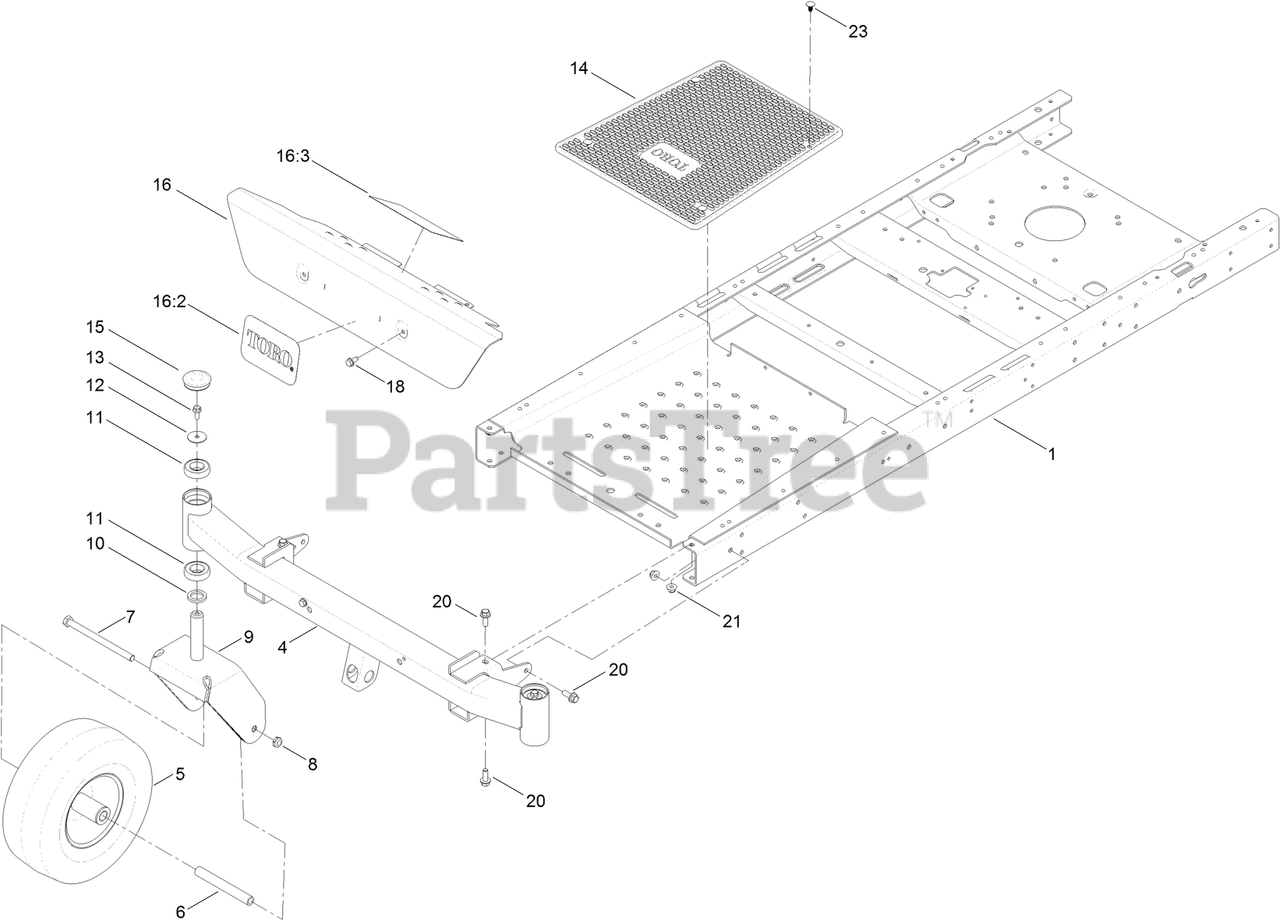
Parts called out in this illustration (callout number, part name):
1	FRAME ASM
4	AXLE ASM
5	13 INCH WHEEL AND TIRE ASM
6	SPANNER
7	SCREW-HH
8	NUT-HEX
9	FORK-CASTER
10	WASHER-THRUST
11	BEARING-BALL
12	WASHER-FLAT
13	SCREW-HHF
14	MAT-FLOOR
15	CAP-GREASE
16	FOOTREST ASM
16:2	DECAL
16:3	DECAL-DANGER
18	SCREW-HWHTF
20	SCREW-HHF
21	NUT-HF, NI
23	PLUG-PLASTIC
